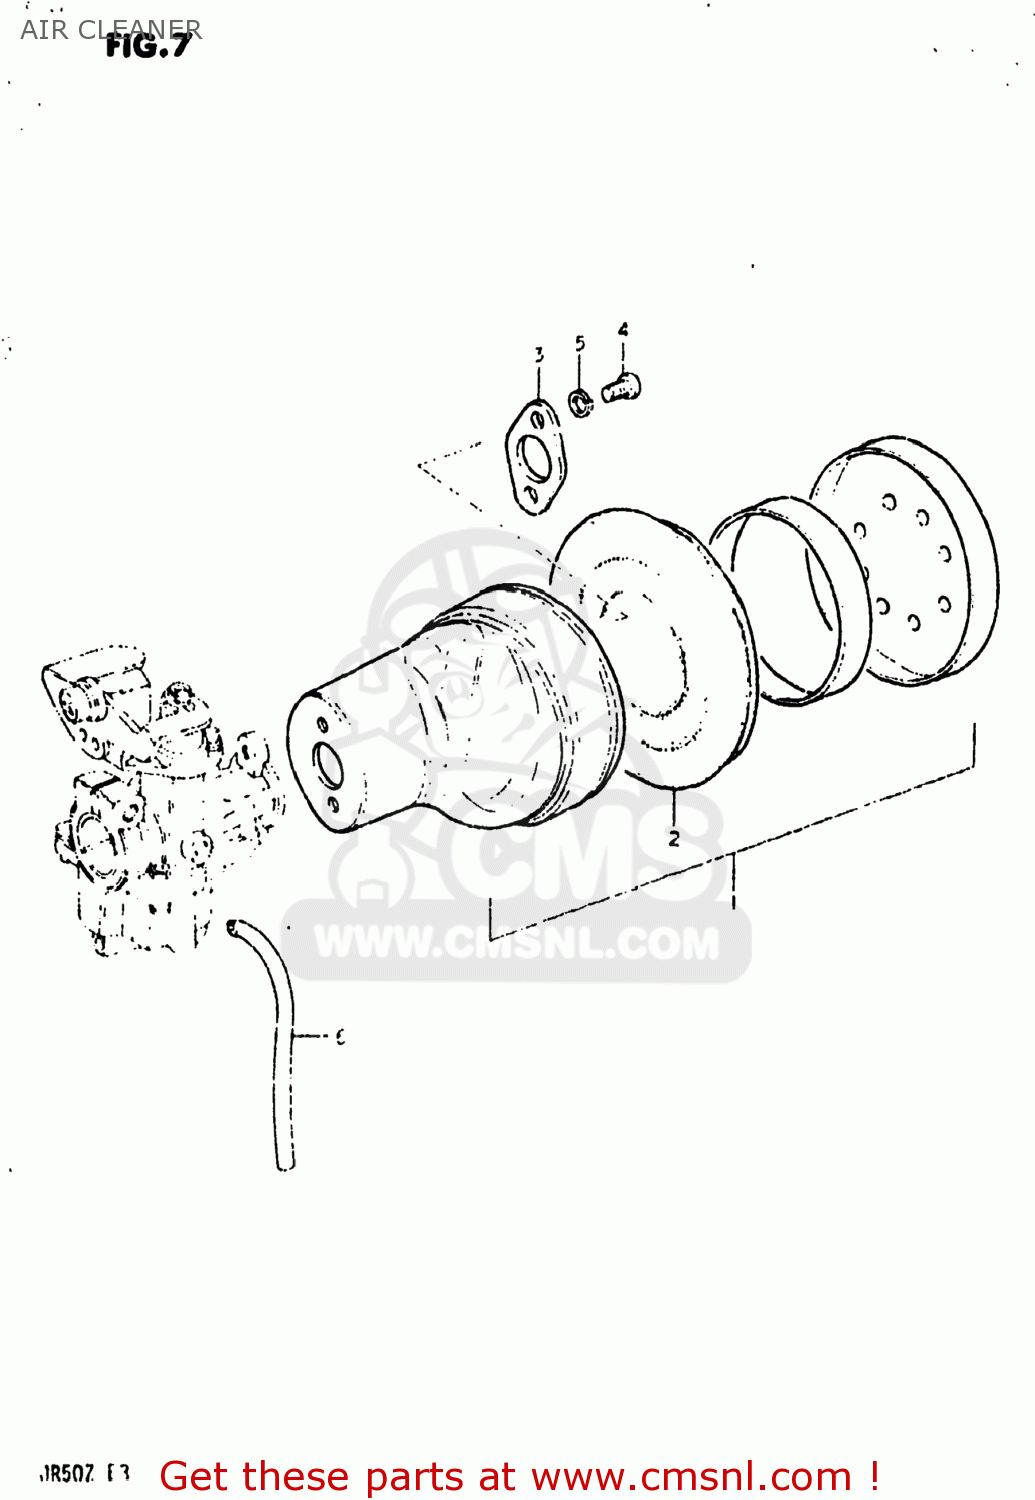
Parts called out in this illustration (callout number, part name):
1	CLEANER ASSY,AIR
2	FILTER,AIR CLEANER
3	PLATE,AIR CLEANER
4	SCREW
5	LOCK WASHER
6	HOSE
